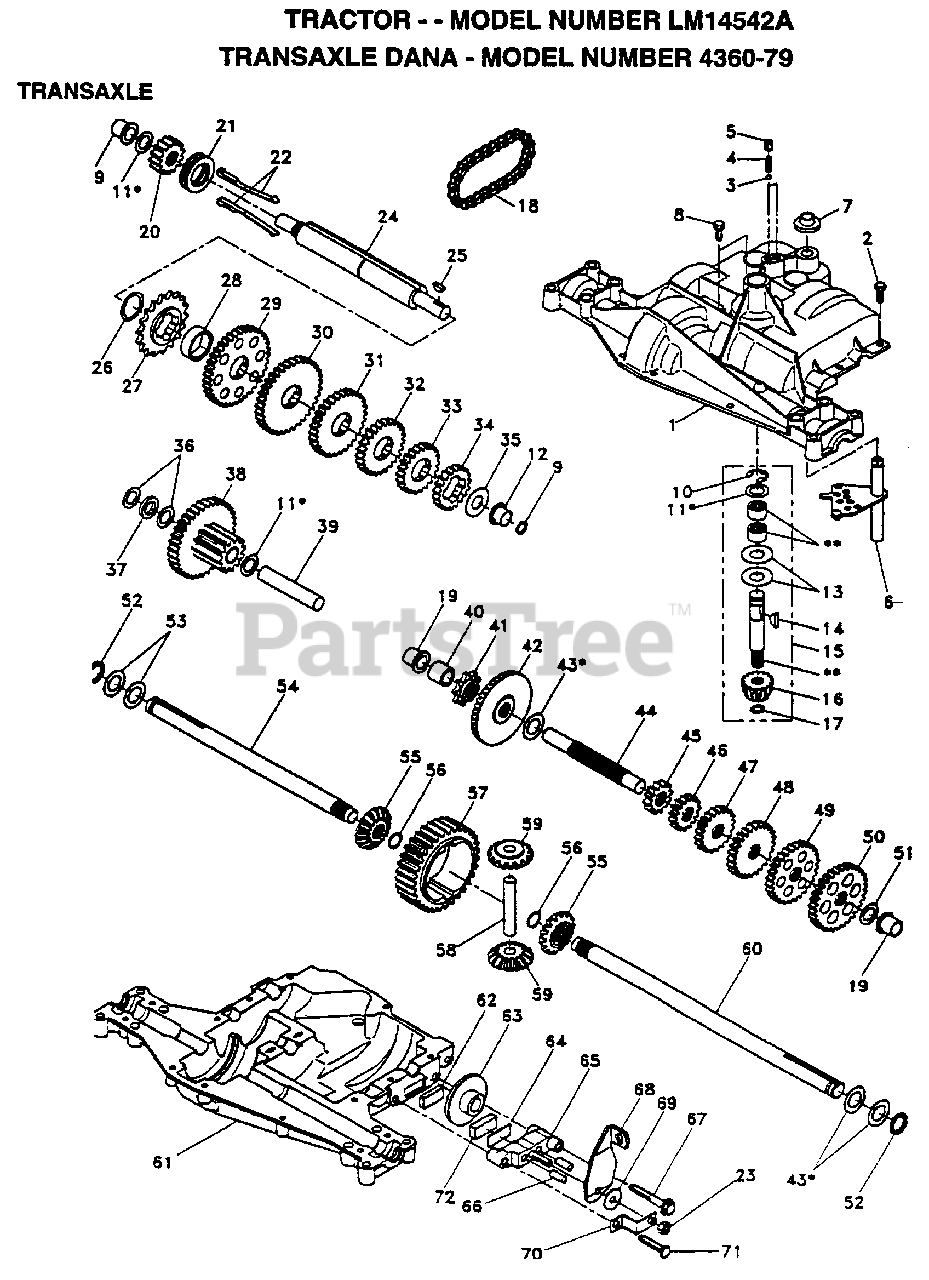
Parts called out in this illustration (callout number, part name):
1	HOUSING UPPER TRN
4	"SPRING, DETENT LT"
5	"SCREW, SET LT"
6	KIT SHIFTER ASM
7	SHIFTER BOOT
8	SCREW TAP W/SEAL
9	SQUARE RING
11	ASM KIT SHIM 4689
12	BEARING FLAN-DANA
13	WASHER T
14	KEY WOODRUFF-DANA
15	AS KIT INPUT SHFT
16	PINION 14T T
17	"RING,RETAINING LT"
18	"CHAIN,24 PTCH LT"
19	BEARING.FLNG.5510
20	GEAR SPUR 14 TTH
21	COLLAR CLUTCH
22	ASM KIT CLTCH KEY
23	NUT.LOCK.5/16-24
24	SHAFT INTERM DANA
25	WOODRUFF KEY
26	"RING,RETAINING LT"
27	SPROCKET 18T T
28	SPACER YT
29	GEAR SPUR 37 TTH
30	GEAR SPUR 35 TTH
32	GEAR 25T LT
33	GEAR SPUR 22 TT
34	SPUR GEAR 19T
35	"WASHER, PLAIN LT"
36	WASHER 025
37	SPACER
38	ASSM GEAR COMB
39	SHAFT IDLER
39	WASHER LT
40	SPACER T
41	SPROCKET 9T LT
43	ASM KIT SHIM
44	SHAFT T
45	GEAR SPUR 12 TTH
46	GEAR SPUR 15 TTH
48	"GEAR, SPUR 25T LT"
49	GEAR 28T T
50	"GEAR, SPUR 31T LT"
51	WASHER 060
52	NEOPRENE WASHER
53	WASHER 031
55	GEAR 15T T
56	"RING,RETAINING LT"
58	SHAFT T
59	GEAR 1ST T
61	HOUSING LOWER TNS
62	PUCK T
63	BRAKE DISC. T
64	SPACER LT
66	PIN T
68	MANUAL.P.WE1442A
71	"SCREW, TAPPING LT"
72	PUCK T
